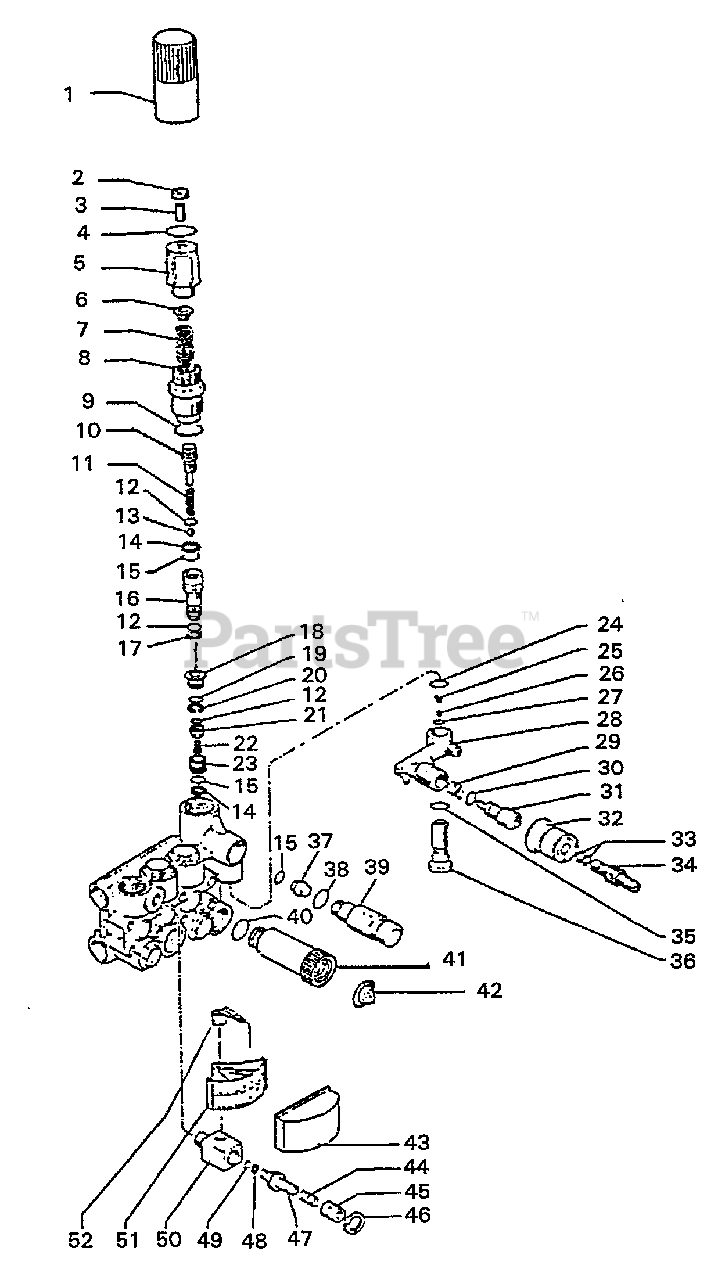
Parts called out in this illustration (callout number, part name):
1	VALVE
2	NUT - 8
3	SCREW M8×16
4	O-RING 20 35×1 78
5	SCREW, PRESSURE SET
6	PLATE, SPRING
7	SPRING
8	BUSHING, GUIDE
9	O-RING 0.797×.103
10	STOPPER, STROKE
11	SPRING
12	O-RING
13	BALL - 9/32"
14	RING, ANTI-EXTRUSION
15	O-RING 9 92×2 62
16	PISTON, CONTROL
17	RING, ANTI-EXTRUSION
18	GUIDE, VALVE
19	O-RING
20	RING, ANTI-EXTRUSION
21	VALVE, BALL
22	SCREW M5×8×75
23	SEAT, VALVE
24	O-RING
25	SPRING, TAPER
26	BALL
27	O-RING 5 28×1 78 VITON
28	INJECTOR BODY
29	SPRING
30	O-RING
31	SHUTTER, INJECTOR
32	KNOB, CHEMICAL REGULATOR
33	O-RING
34	FITTING, HOSE BARB
35	O-RING
36	SEAT, CHEMICAL VALVE
37	NOZZLE, INJECTOR
38	O-RING 13 95×2 62
39	FITTING, GREASE
41	FITTING, GREASE
43	COVER
44	SPRING
45	SCREW M14×1
46	NUT M14×1×17×3
47	PISTON
48	RING
49	O-RING 3 63×1 78 VITON
50	BODY
51	DIAL
52	INDICATOR
